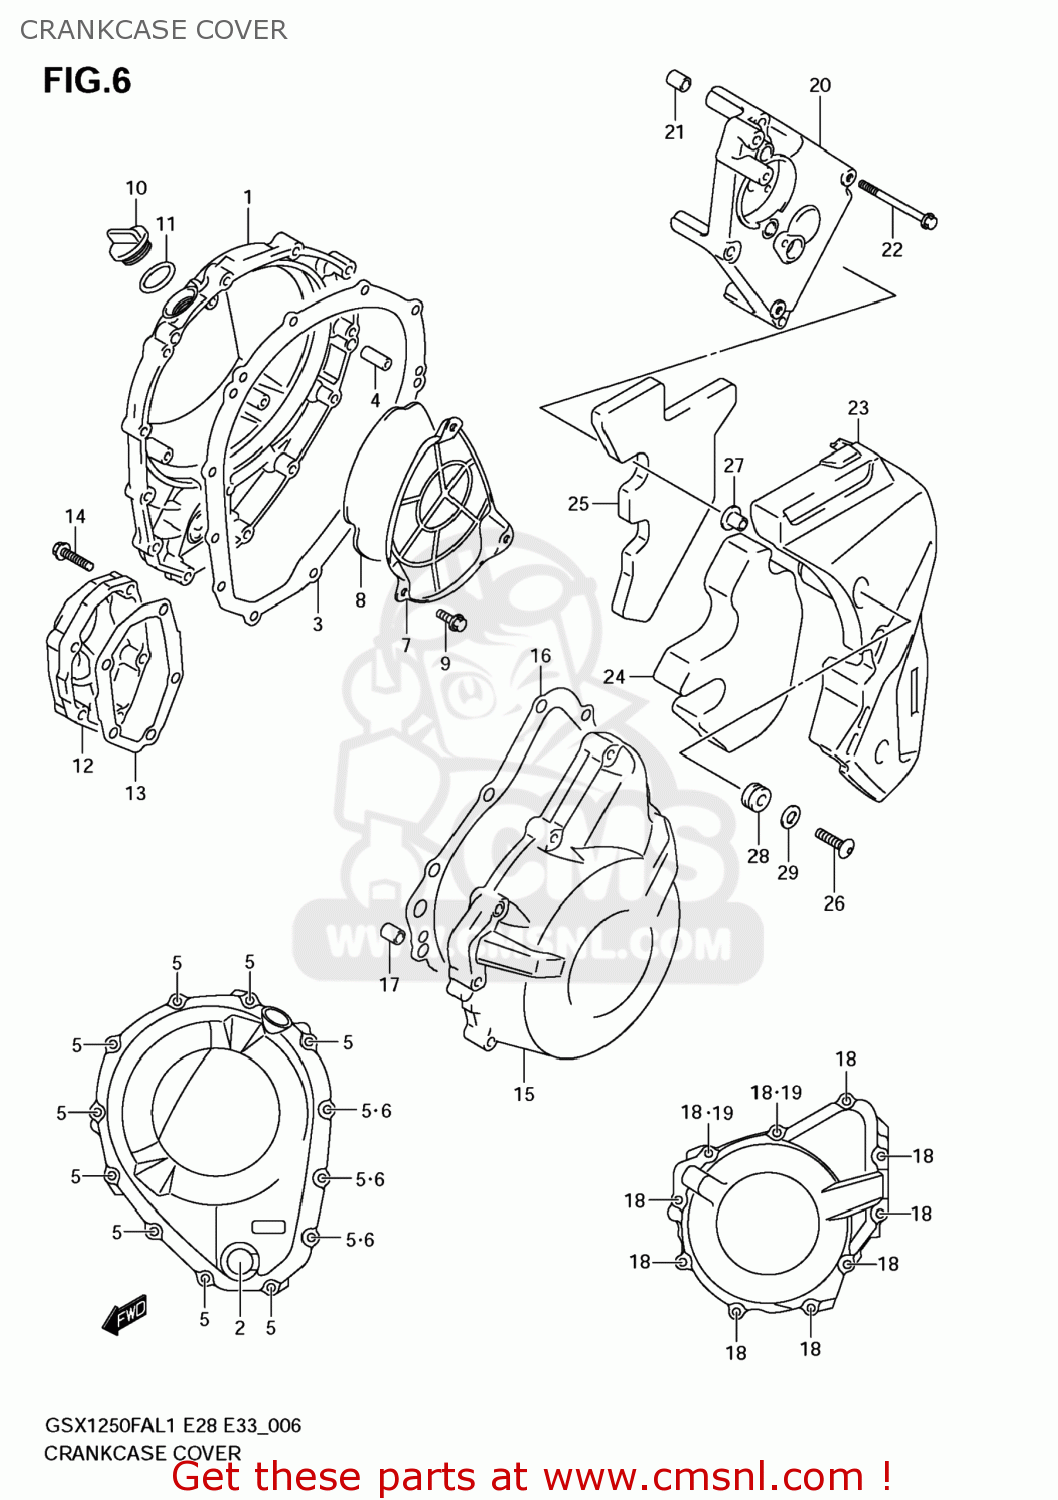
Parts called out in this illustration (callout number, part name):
1	COVER,CLUTCH
2	LENS,OIL LEVEL CHECK
3	GASKET,CL COVER (NAS)
4	PIN
5	BOLT(6X30)
6	GASKET(5.8X13X1.2) (NAS)
7	PLATE,CLUTCH COVER
8	DAMPER,CLUTCH COVER
9	BOLT
10	PLUG,ENGINE OIL FILLER
11	O RING(D:3.1,ID:16.8)
12	COVER,CRANKSHAFT,R
13	GASKET,CRANKSHAFT,R COVER (NAS)
14	BOLT(6X30)
15	COVER,MAGNETO
16	GASKET,MAGNETO COVER (NAS)
17	PIN
18	BOLT(6X30)
19	GASKET(5.8X13X1.2) (NAS)
20	COVER,ENGINE SPROCKET INNER
21	PIN
22	BOLT
23	COVER,ENGINE SPROCKET OUTER
24	CUSHION,ENG SPRKT COVER NO.1
25	CUSHION,ENG SPRKT COVER NO.2
26	SCREW(6X25)
27	WASHER
28	CUSHION
29	WASHER(6.5X16X1.2)
